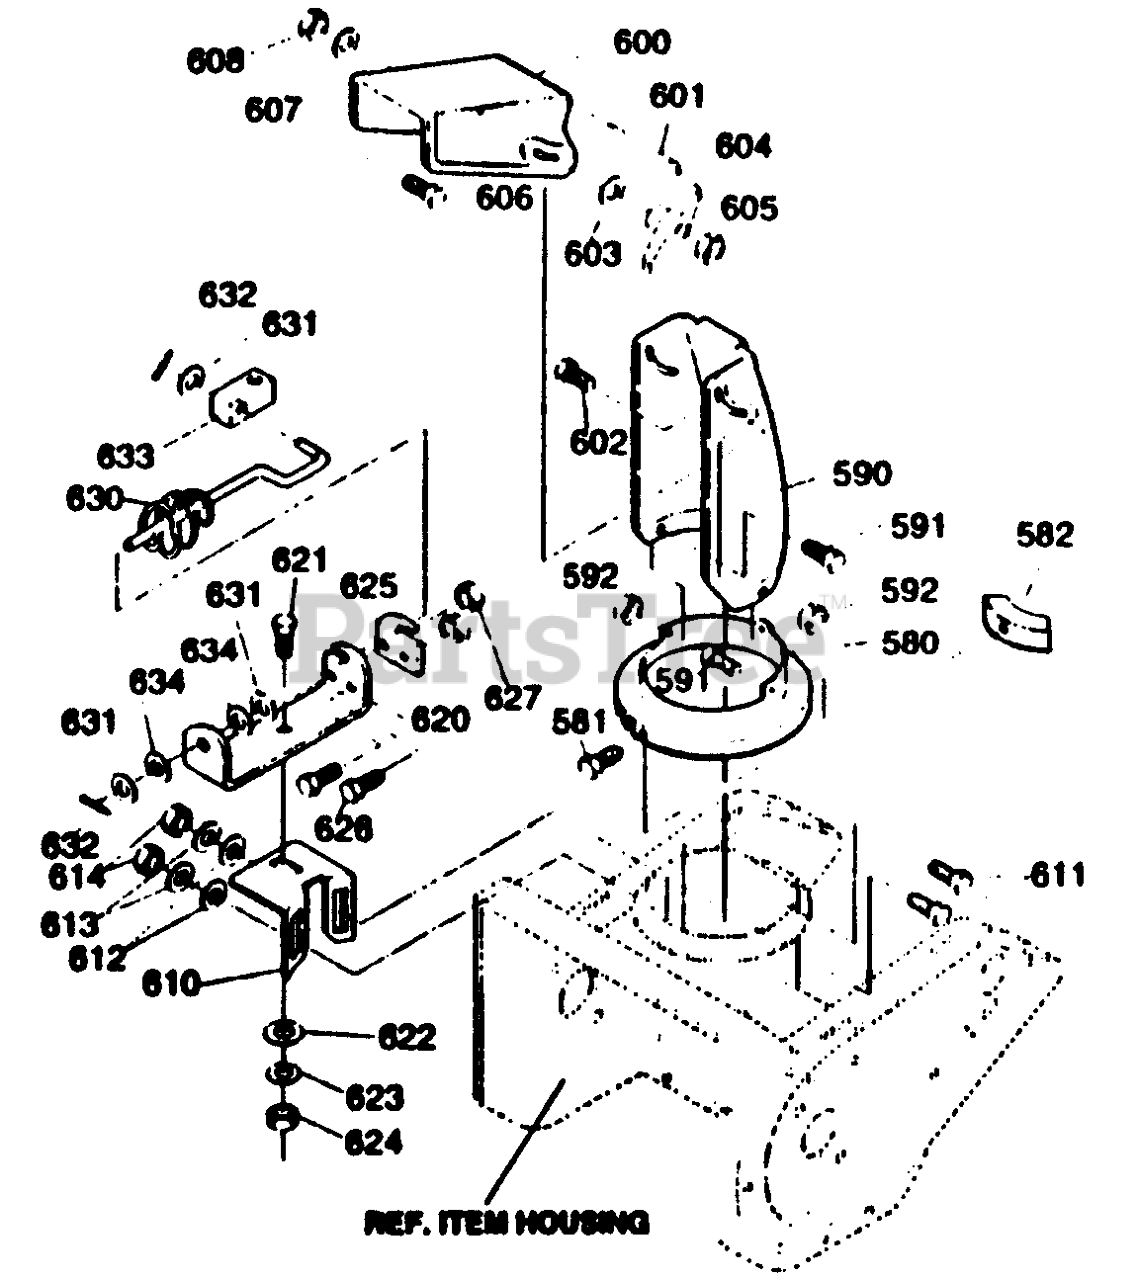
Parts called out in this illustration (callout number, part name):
580	RING, LOWER CHUTE
581	SCREW, 1/4-14X.63 HWATAP
582	CLIP, CHUTE RING PLASTIC
590	CHUTE, LOWER
591	SCREW, 1/4-20X .50 HHC
592	BOLT, 3/8-16X2.00 CARR
600	CHUTE, UPR SRS W/O HDLE
601	WIRE, HINGE
603	WASHER, FLAT .344X .69X.
604	KNOB, W/NUT
605	NUT, 5/16-18 REGHEX
606	NUT, 5/16-18
607	WASHER, FLAT .344X .69X.
608	NUT, 5/16-18 REGHEXCTRLK
610	MP BRACKET, WORM ADJ
612	WASHER, FLAT .344X .69X.
613	WASHER, HVSPTLK .328X.60X
614	NUT, 5/16-18 REGHEX
620	BRACKET, CHUTE ROD HOLDER
622	WASHER, FLAT .344X .69X.
623	WASHER, HVSPTLK .328X.60X
624	NUT, 5/16-18 REGHEX
625	PLATE, CHUTE ROD
626	SCREW, 1/4-20X .50 HHC
630	ROD, ASSY CHUTE LWR
631	WASHER, FLAT .40X.75X.025
632	SCREW, 5/16-18X2.25 HHC
633	BLOCK, PIVOT PLASTIC
